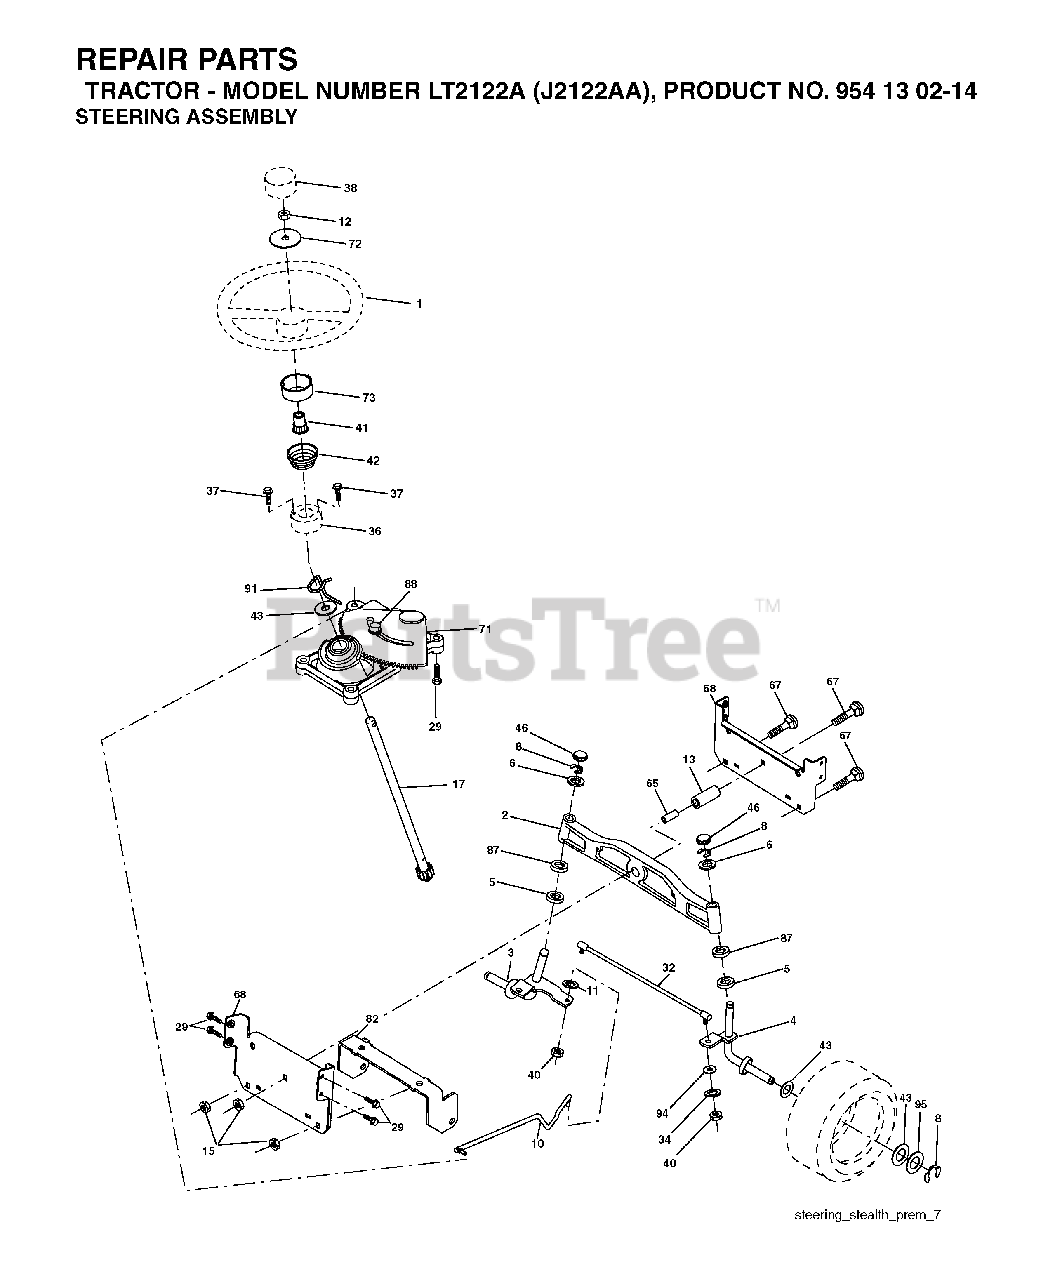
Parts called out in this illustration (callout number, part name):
2	AXLE ASSY FRONT
3	SPINDLE.ASM.LH.15"TIRES
4	SPINDLE.ASM.RH.15"TIRES
8	RING CLIP
10	DRAGLINK.15".TIRES.2001
11	WASHER, LOCK 3/8
12	NUT.HEX.1/2-20
13	TUBE, PIVOT AXLE
15	NUT
17	SHAFT ASM STRG
29	SCREW, 3/8-16X3/4
32	ROD TIE BALL J
34	WASHER, LOCK 3/8
36	BUSHING, STRG. BLK
40	NUT CROWNLOCK 3/8-24
41	STEERING WHEEL ADAPTOR
46	CAP.SPINDLE
65	SPACER BRACE AXLE
67	BOLT CARRIAGE
68	BRACE.AXLE.15"TIRES
71	STEERING ASM
82	BRACKET
87	WASHER, FLAT .781 X 1 1/2"
88	BOLT, SHOULDER 7/16-20
91	CLIP.STEERING
94	WASHER
95	WASHER.HARDENED
